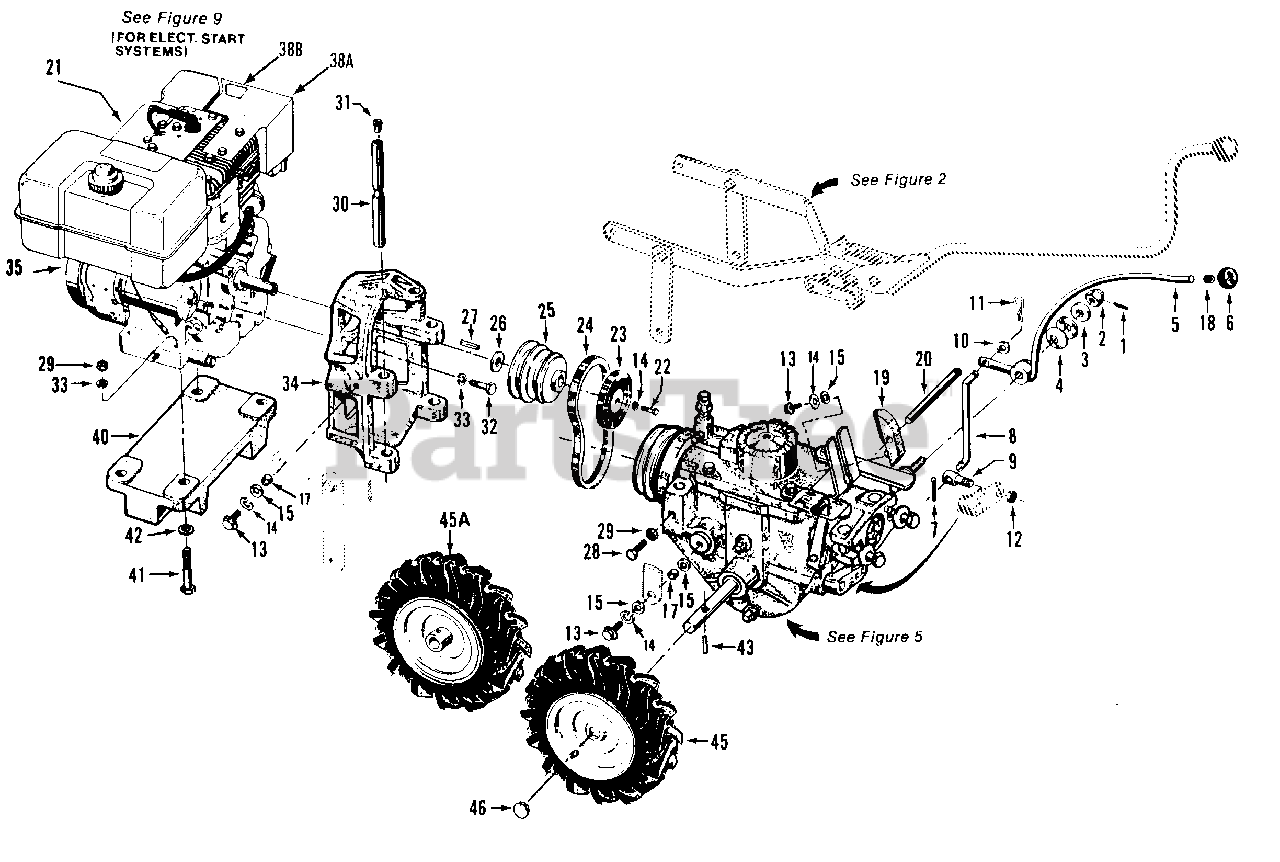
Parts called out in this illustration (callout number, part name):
1	Pin-spring, 1/8"
2	Nut-castle (slotted), 1/2"-20
3	Washer-shoulder, 1/2"
4	Washer-disc spring
5	Lever-wheel speed shift
6	Knob-wheel speed shift lever
7	Pin-cotter, 3/32" x 1"
8	Rod-connecting rod, wheel speed shift lever
9	Swivel-connecting rod
10	Washer-flat, 5/16", S.A.E
11	Pin-hair cotter
12	Locknut-hex hd., 5/16"-18
13	Bolt-flanged hex hd., 3/8-16 x 1"
14	Lockwasher-spring lock, 3/8"
15	Washer-flat, 3/8", S.A.E
17	Bushing-spacer, 19/64" (.300" lg.)
18	Ring-retaining
19	Block-belt adjustment, 3-7/8"
20	Rod-belt adjust., 7" with measuring gauge
21	Decal-engine stabilization, for Briggs & Stratton engines
22	Bolt-hex hd., 3/8-24 x 1-1/2"
23	Disc-reverse
24	Belt-forward drive
25	Pulley-engine power take off
26	Shim-engine pulley, 1/16"
26	Shim-as above, 1/32"
27	Key-engine pulley, 3/16"sq. x 2-1/2"
28	Bolt-hex hd., 5/16-18 x 1", Grade 5
29	Nut-hex, 5/16"-18
30	Bar-engine mounting
31	Plug-thread protector, red plastic
32	Bolt-hex hd., 5/16-24 x 1-1/8"
33	Lockwasher-spring lock, 5/16"
34	Mount-engine to tiller
35	7HP Briggs & Stratton Engine-Recoil or electric start.
35	8HP Briggs & Stratton Engine-Recoil or electric start.
38A	Muffler Guard
38B	Decal-hot surface safety warning
40	Engine Weight-for Briggs & Stratton engines only
41	Bolt-hex hd., 5/16-18 x 2-1/4", Grade 5
42	Spacer-zinc plated
43	Pin-roll, 5/16" x 1-1/2"
45	Wheel & Tire Assy-bar tread, left side
45A	Wheel & Tire Assy-bar tread, right side.
46	Cap-wheel hub
